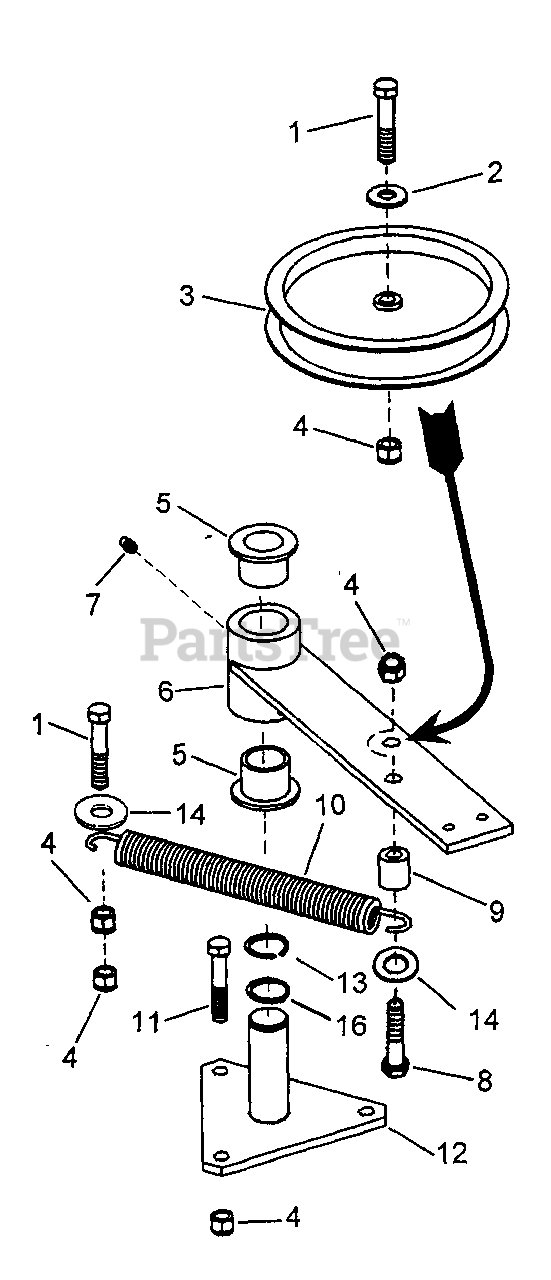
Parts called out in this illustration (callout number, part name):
1	BOLT, 3/8-16 X 2, GD5, CZ
2	WASHER, 3/8" USS
3	PULLEY, Idler 5-1/2" O.D.
4	NUT, 3/8-16 HEX NYLON LOCK
5	BUSHING
6	ARM, Idler (Weldment)
7	FITTING, Lube 1/4-28 Straight
8	SCREW, 3/8-16 x 1-3/4" Hex Head Cap, Grade 5
9	SPACER, .50 I.D. x .75 O.D. x .83
10	SPRING, Extension
11	BOLT, 3/8-16 X 1" GD5 CZ
12	PLATE, Tri-Mount (Weldment)
13	E-RING 1"
14	WASHER, .406 x 1.5 x .120 Yellow Zinc
16	WASHER, 1.031 x 1.25
